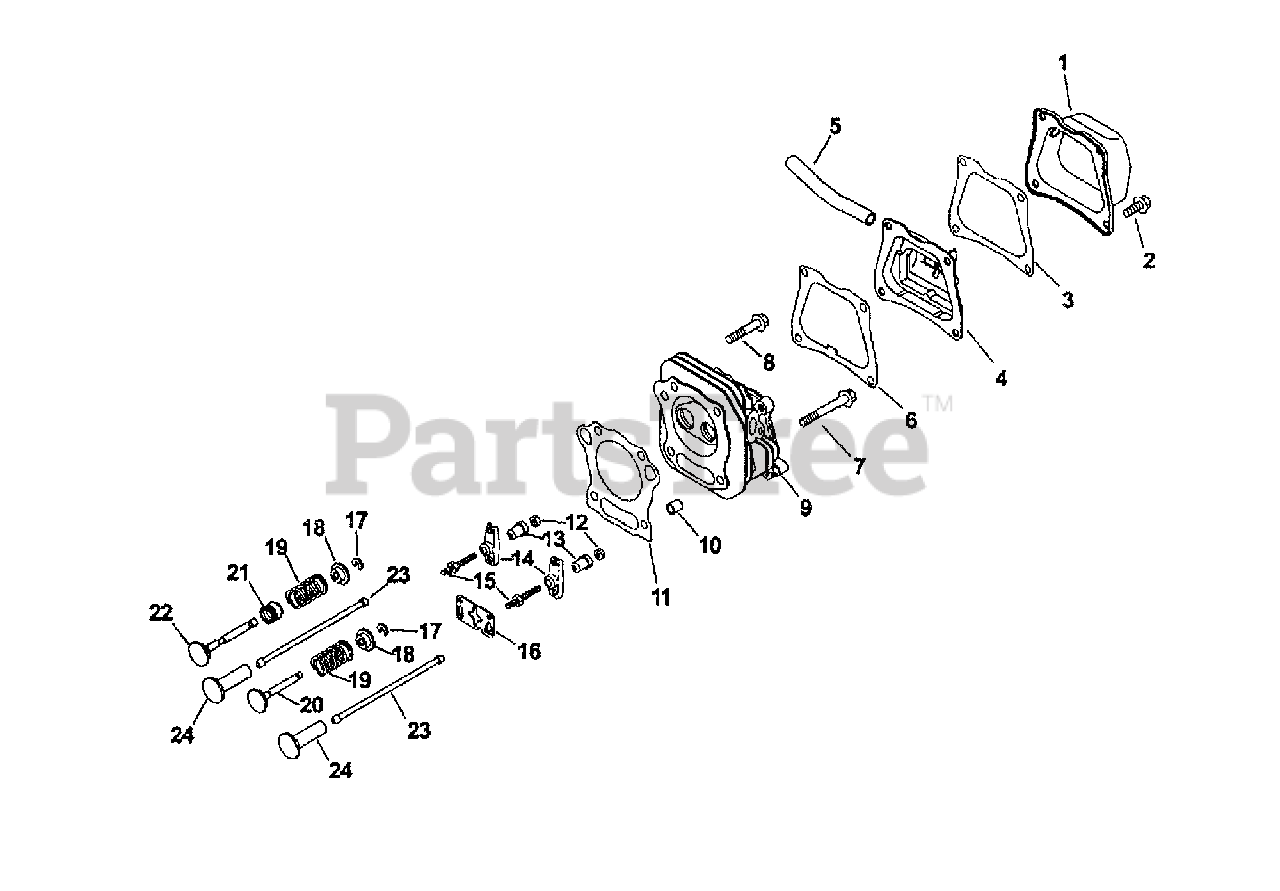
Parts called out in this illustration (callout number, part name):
2	Screw, Valve Cover
3	Gasket, Breather
4	Breather Assembly
5	Hose, Breather
6	Gasket, Breather
7	Screw, Cylinder Head
8	Screw, Cylinder Head
9	Head, Cylinder
11	Gasket, Cylinder Head
13	Pivot, Rocker Arm
15	Screw, Valve Adj.
16	Guide, Push Rod
17	Keeper, Valve
18	Cap, Valve Spring
19	Spring, Valve
20	Valve, Intake
21	Seal, Valve Stem
22	Valve, Exhaust
24	Lifter, Valve
